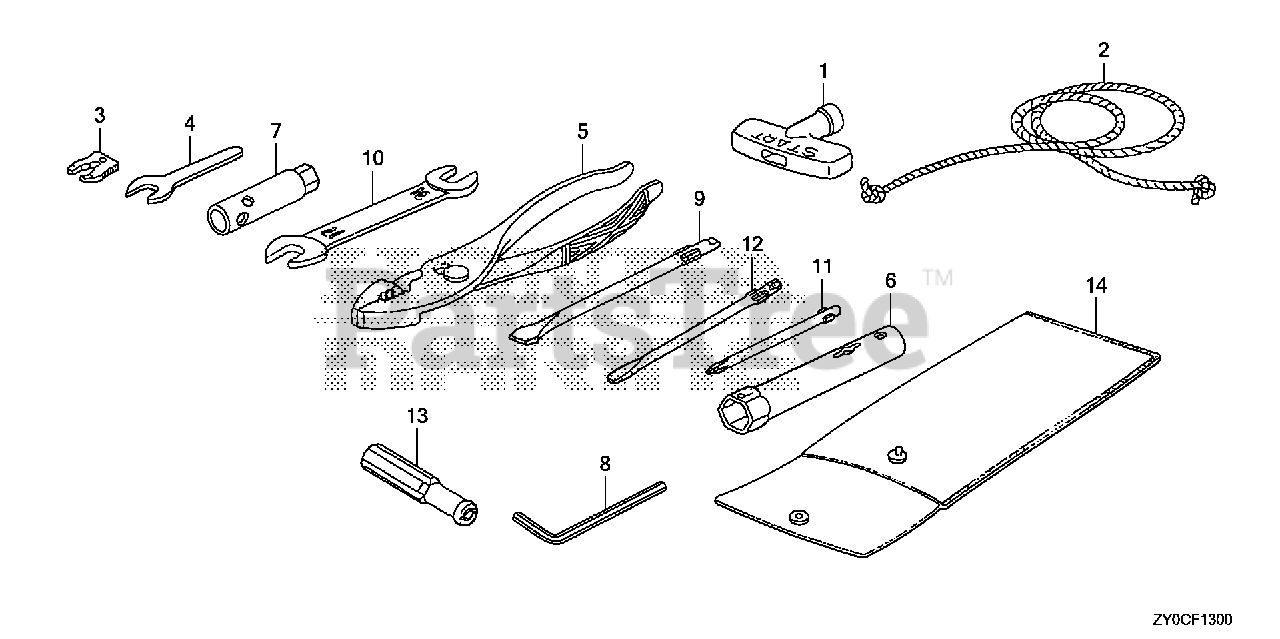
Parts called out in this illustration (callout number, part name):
1	GRIP, STARTER
2	ROPE, RECOIL STARTER (1300MM)
3	CLIP, EMERGENCY LOCK
5	PLIERS (135) (RIKEN)
6	WRENCH, SPARK PLUG
7	WRENCH, BOX (10MM) (NOT AVAILABLE)
8	WRENCH, HEX. (4MM)
9	SCREWDRIVER, CHECK BOLT
10	WRENCH (10X12) (OPEN END)
11	SCREWDRIVER 1, PHILLIPS (NO.2)
12	SCREWDRIVER 3, STRAIGHT SLOT (NO. 2)
13	GRIP, SCREW DRIVER
14	BAG, TOOL (160MM)
